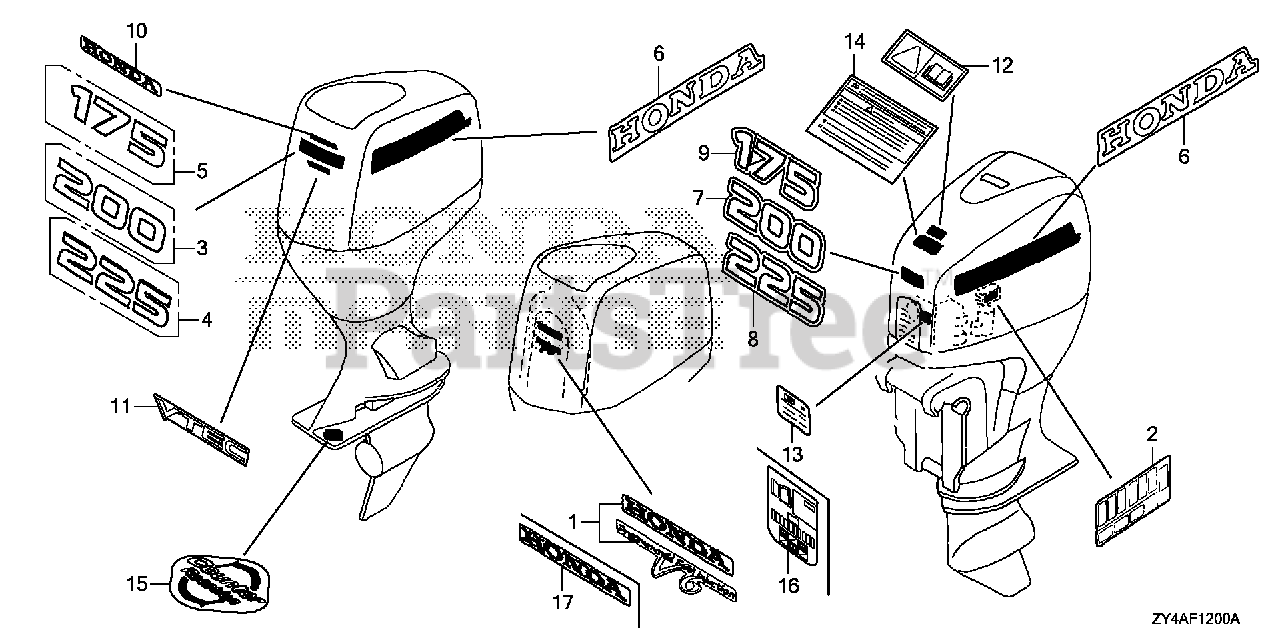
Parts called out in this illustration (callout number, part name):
4	MARK, RR. (BF225)
6	MARK, SIDE STRIPE (HONDA)
8	MARK, FR. EMBLEM (BF225)
10	MARK, HONDA
11	MARK (VTEC)
14	LABEL, WARNING OPERATOR
16	LABEL, FUSE & OIL CAUTION
17	EMBLEM (13 (HONDA)
